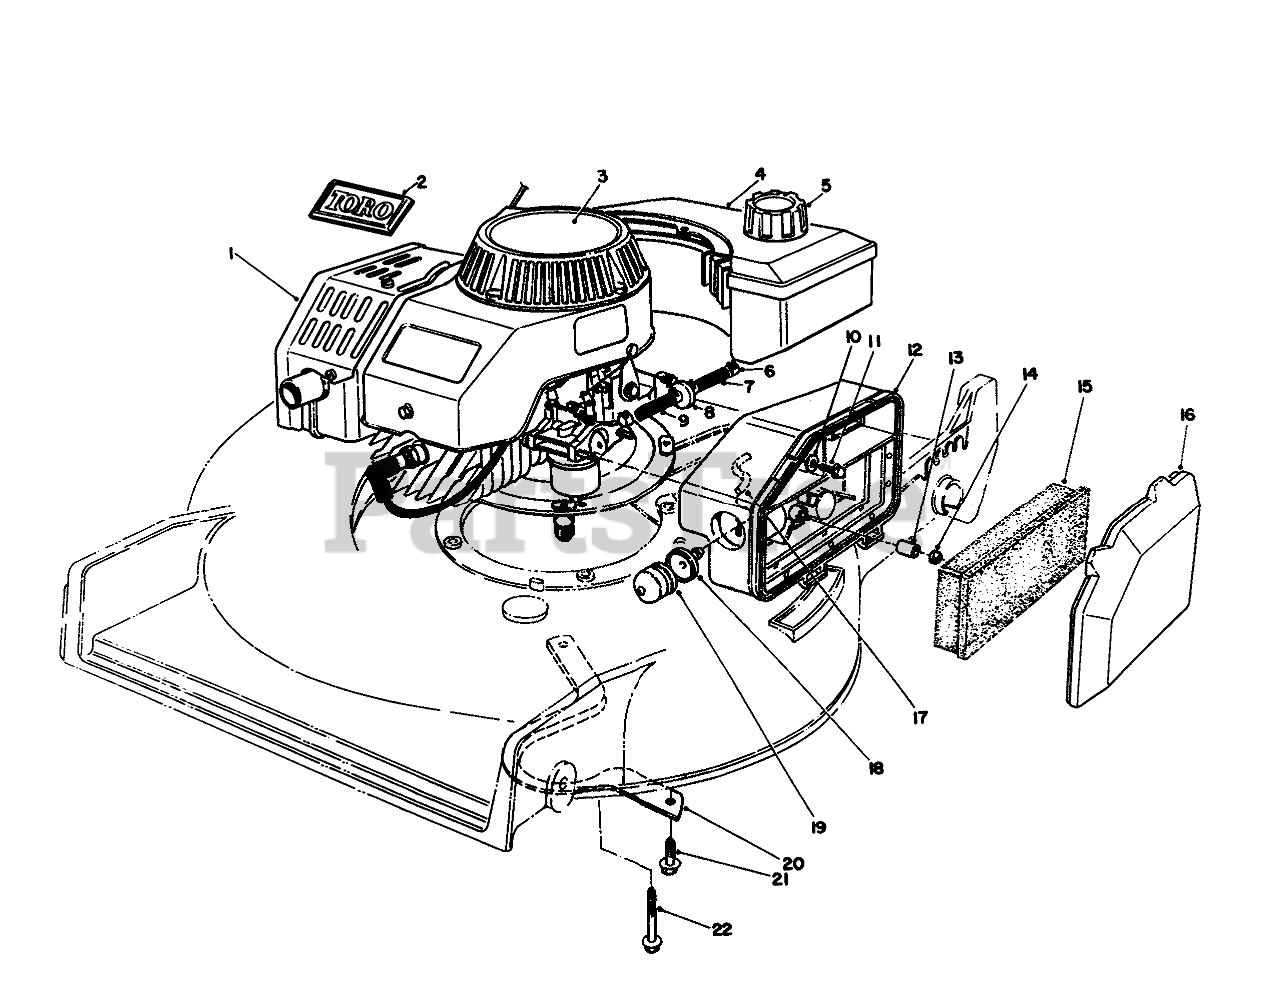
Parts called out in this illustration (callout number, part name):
1	Engine
2	TORO LOGO PLT
3	DECAL - 2 CYC RECOIL
4	Gas Tank Assembly
5	GAS CAP ASM
6	CLAMP-FUEL LINE
7	HOSE-FUEL
8	FILTER-FUEL
9	HOSE-FUEL
10	WASHER-FLAT
11	SCREW-HH
12	BODY-AIR CLEANER
13	SPACER
15	ELEMENT-AIR CLEANER
16	COVER-AIR CLEANER
17	HOSE-PRIMER
18	BODY-PRIMER
19	BULB-PRIMER
20	Guide-Belt
21	SCREW-HWHTF
22	SCREW-HHF
